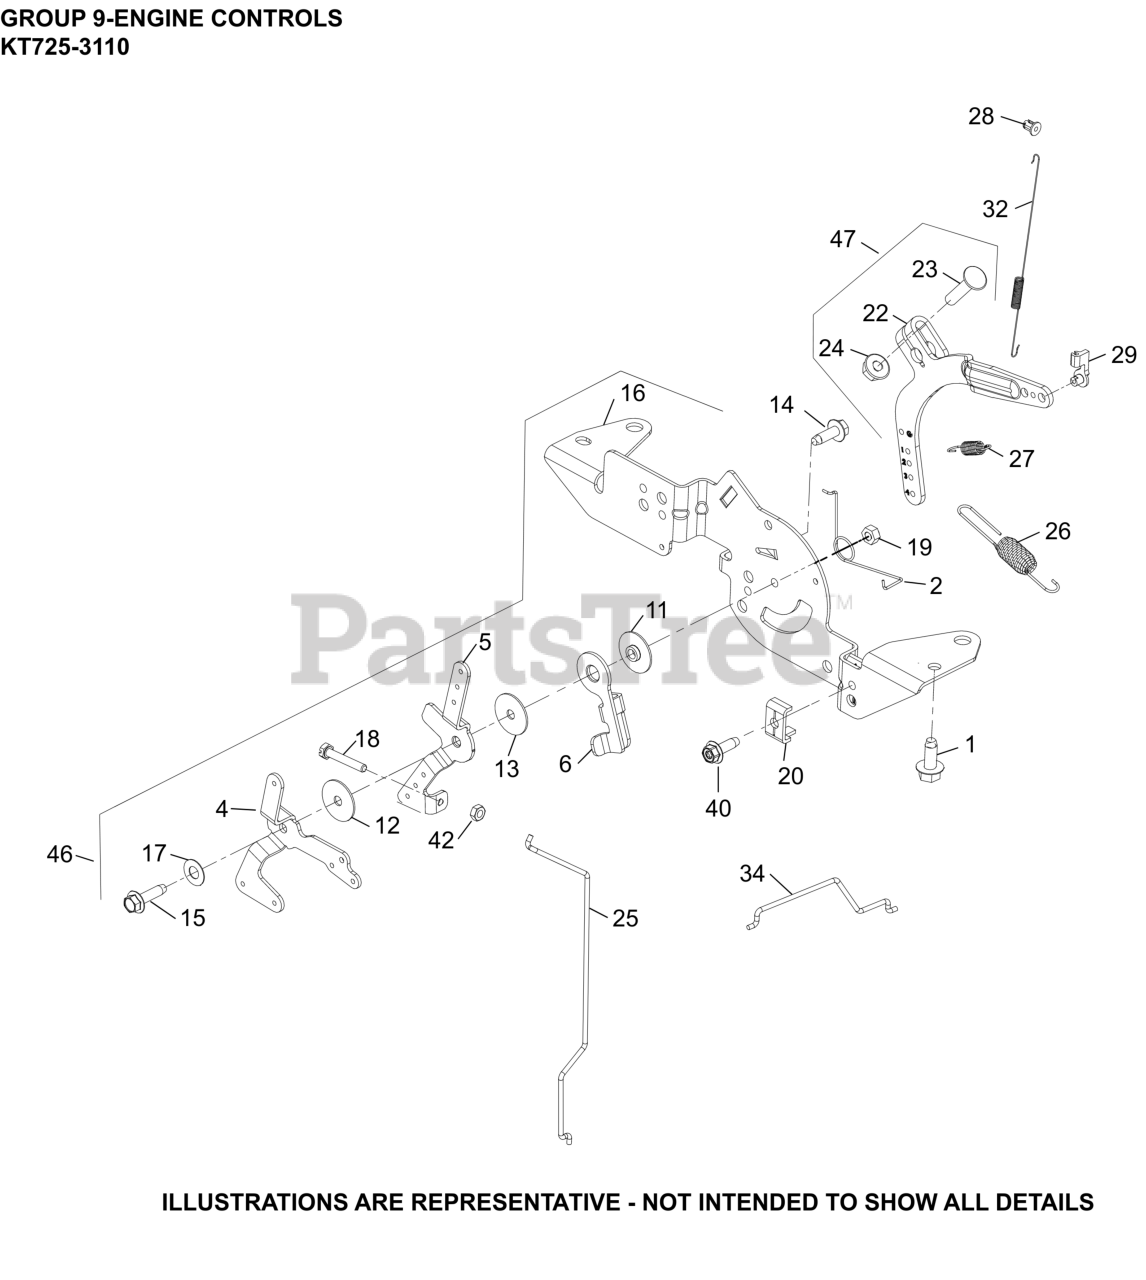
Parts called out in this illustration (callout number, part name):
1	SCREW, THREAD FORMING
2	SPRING, CHOKE RETURN
4	LEVER, CHOKE
5	LEVER, THROTTLE CONTROL
6	LEVER, THROTTLE ACTUATOR
11	SPACER, CONTROL ASSEMBLY
12	WASHER, FLAT 5.5 MM
13	WASHER, FLAT 5 MM
14	SCREW, THREAD FORMING
15	SCREW, THD FRM-USE 25 086 473-S
16	BRACKET, SPEED CONTROL
17	WASHER, SPRING 1/4"
18	SCREW, SLT HD CAP M4X0.7X25
19	NUT, LOCK M5X.8
20	CLAMP, CABLE CABLE
22	LEVER, GOVERNOR - (#2409069S)
23	BOLT, RD HD SQ NECK M6X1.0X25
24	NUT, FLG M6X1.0
25	LINKAGE, CHOKE
26	SPRING, GOVERNOR (ORANGE)
27	SPRING, GOVERNED IDLE
28	BUSHING, LINKAGE RETAINING
29	BUSHING, THROTTLE LINKAGE
32	SPRING, LINKAGE
34	LINKAGE, THROTTLE
40	SCREW, THREAD FORMING
42	NUT, M4X0.7
46	CONTROL ASSEMBLY, DUAL WIRE
47	LEVER, GOVERNOR ASSEMBLY
